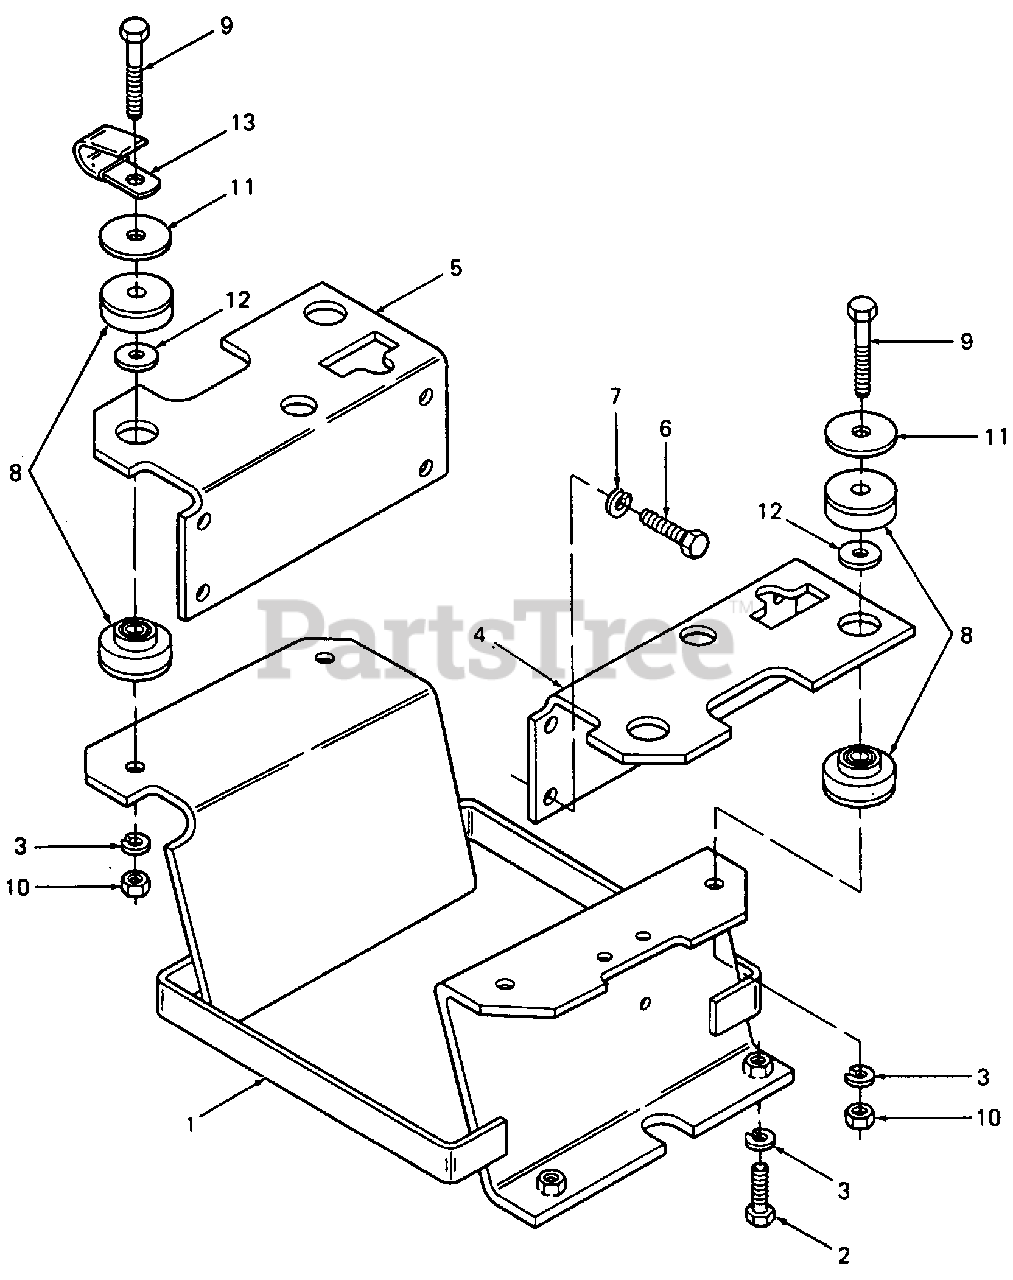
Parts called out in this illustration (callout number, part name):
3	Washer, Lock, 3/8
7	Washer, Lock, 10.2 mm
8	Isomount
9	Screw, Hex Cap, 3/8-16 X 2.25 Lg GR5
10	Nut, Hex, 3/8-16 GR5
11	Washer, Flat, .390 X 1.50 X .134 Thk
12	Washer, Isomount, .38 X .93 X .110 Thk Hdn
13	Clip, Cable
